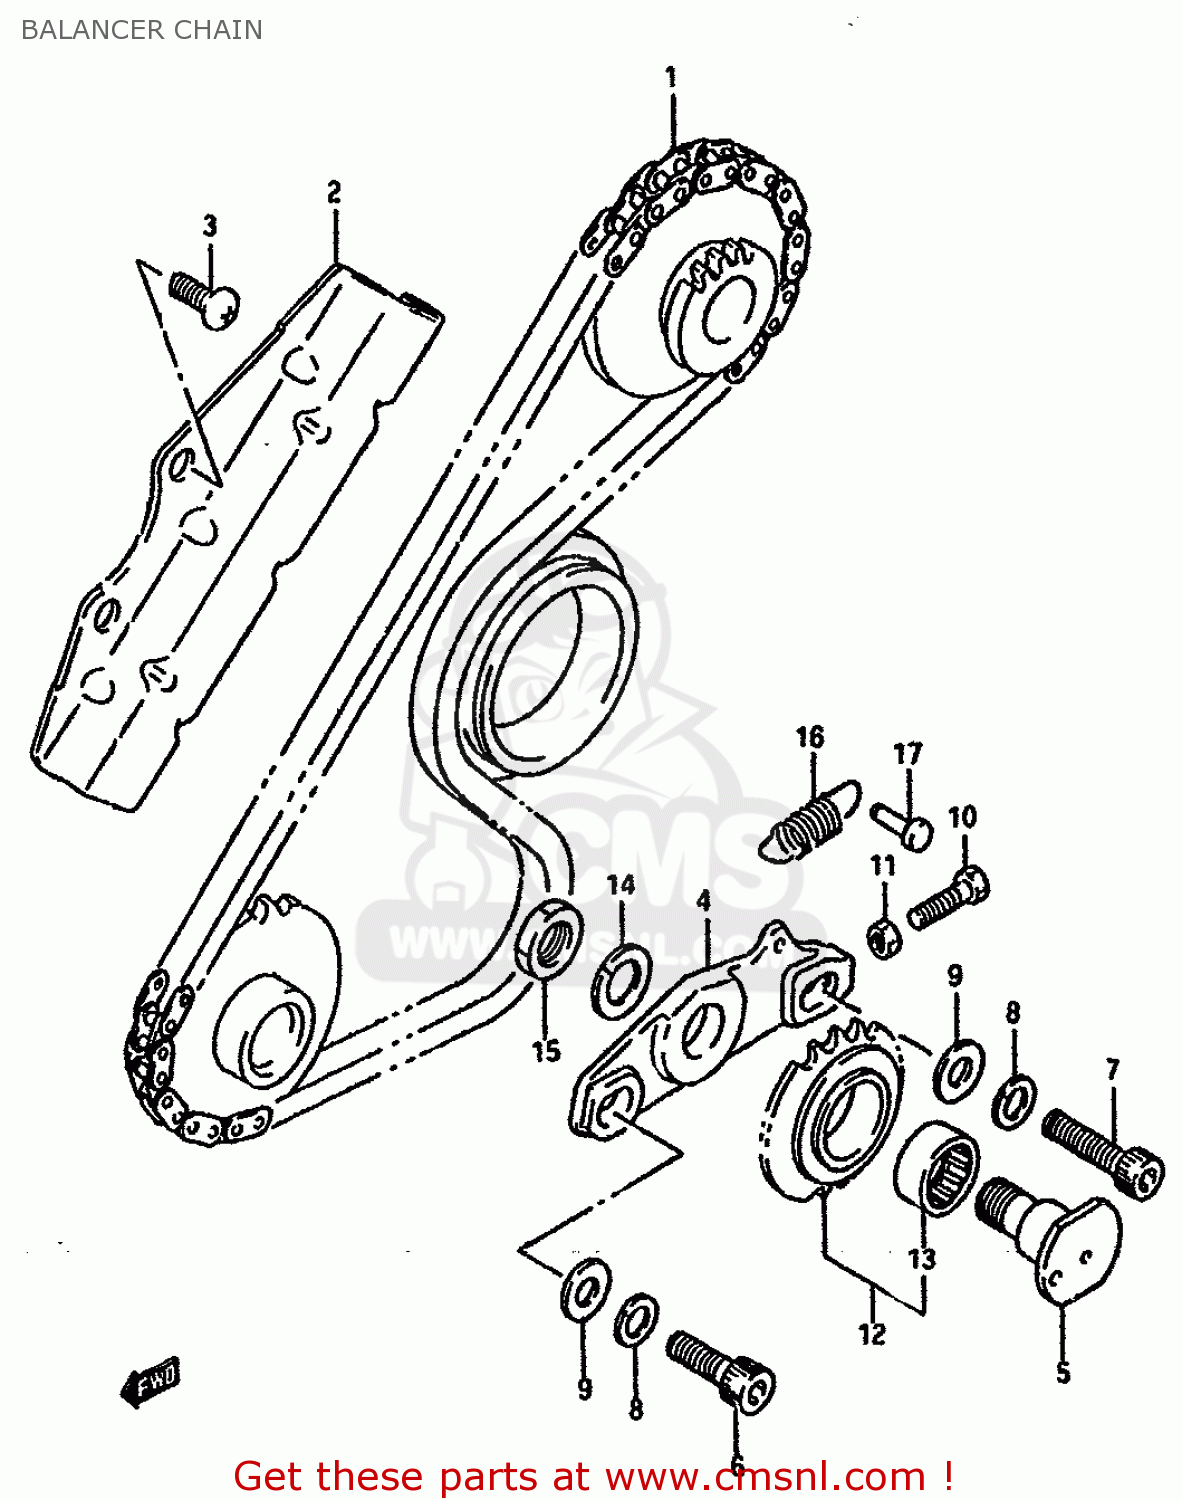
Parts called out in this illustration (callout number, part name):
1	CHAIN,BALANCER
2	GUIDE,BALANCER CHAIN
3	SCREW
4	BRACKET, CHAIN TENSIONER
5	SHAFT,BALANCER CHAIN TENSIONER
6	BOLT(8X22)
7	BOLT, REAR (8X30)
8	LOCK WASHER
9	WASHER
10	BOLT 5X20
11	NUT
12	SPRKT,BALANCER CHAIN TENSIONER
13	BEARING(17X23X12)
14	WASHER,LOCK 12
15	NUT
16	SPRING
17	RIVET
